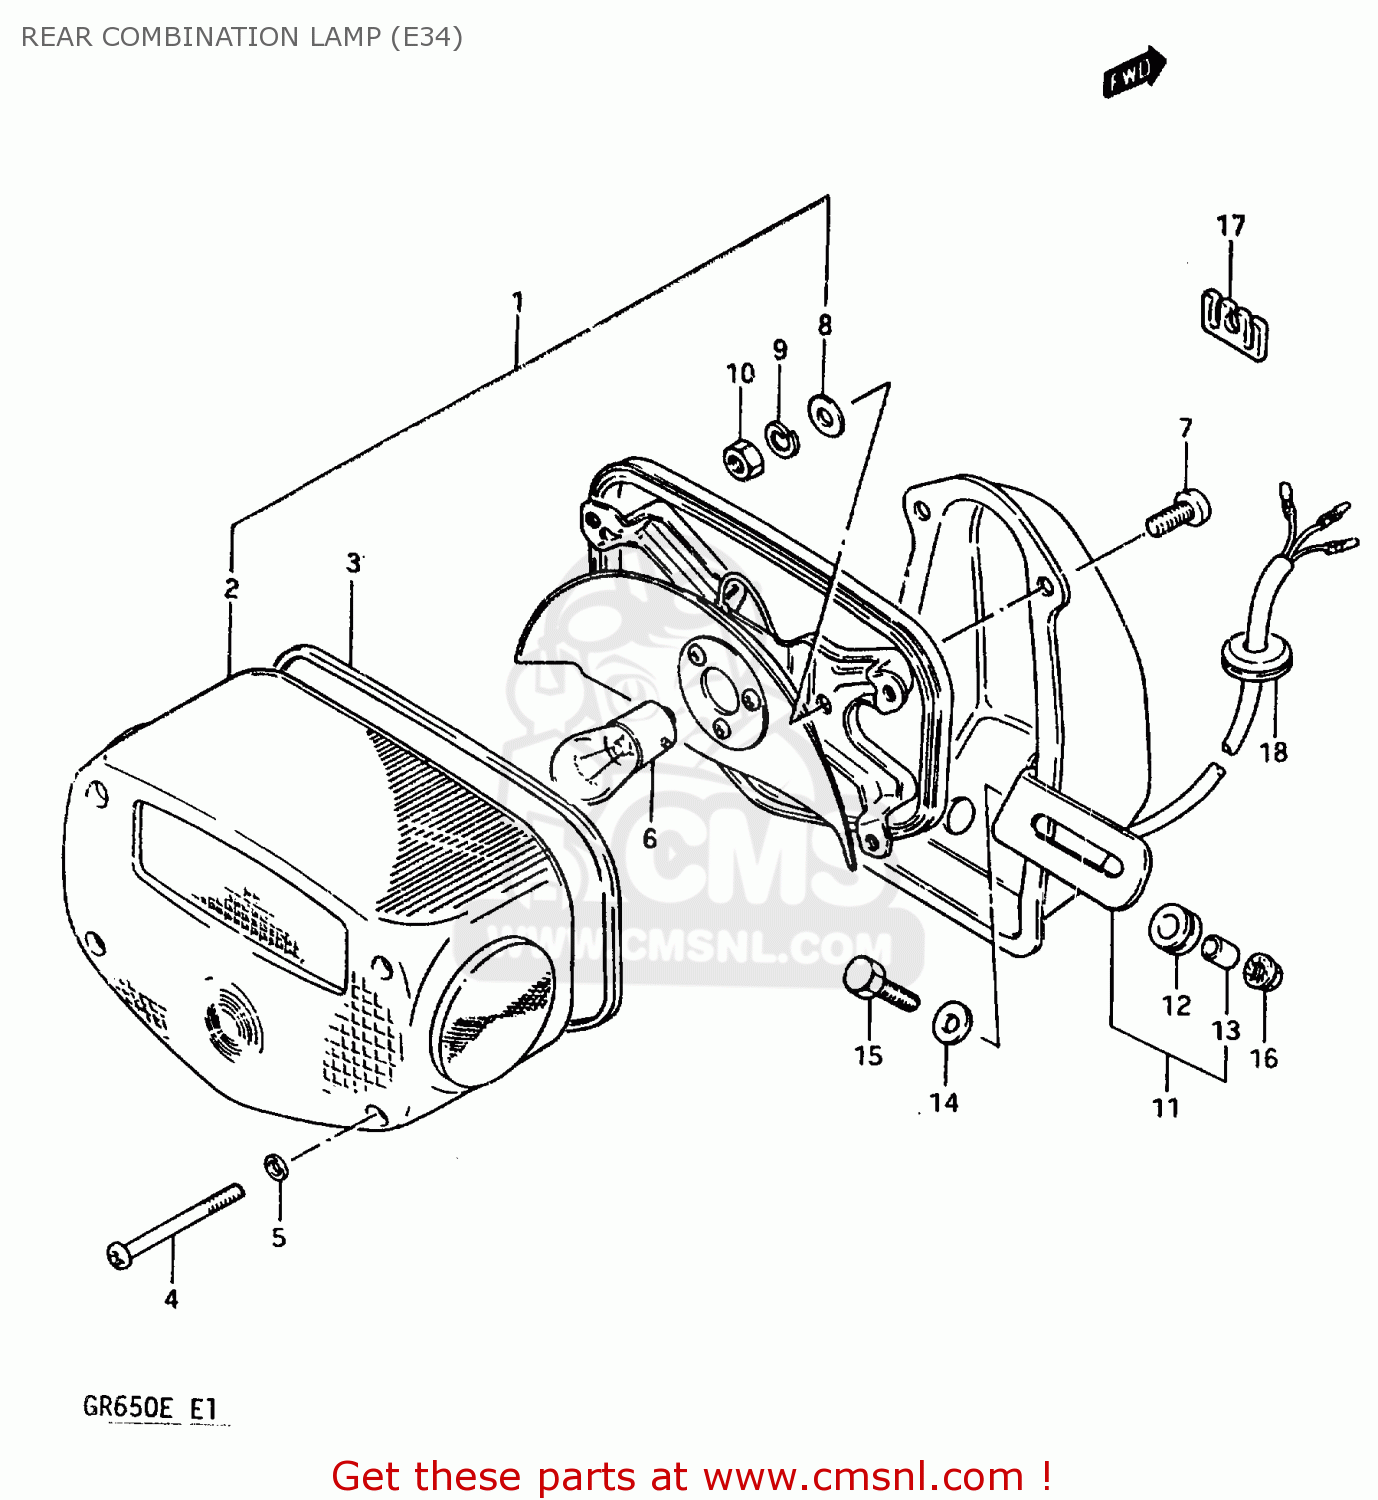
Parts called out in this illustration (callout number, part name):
1	LAMP UNIT, REAR COMBINATION
2	LENS
3	GASKET (NAS)
4	SCREW (4X55)
5	GASKET (NAS)
6	BULB(12V21/5W)
7	SCREW 6X12
8	WASHER
9	LOCK WASHER
10	NUT
11	BRACKET ASSY
12	CUSHION
13	SPACER
14	WASHER (6.5X20X1.2)
15	BOLT
16	NUT 6MM
17	GUIDE,WIRING HARNESS
18	GROMMET
